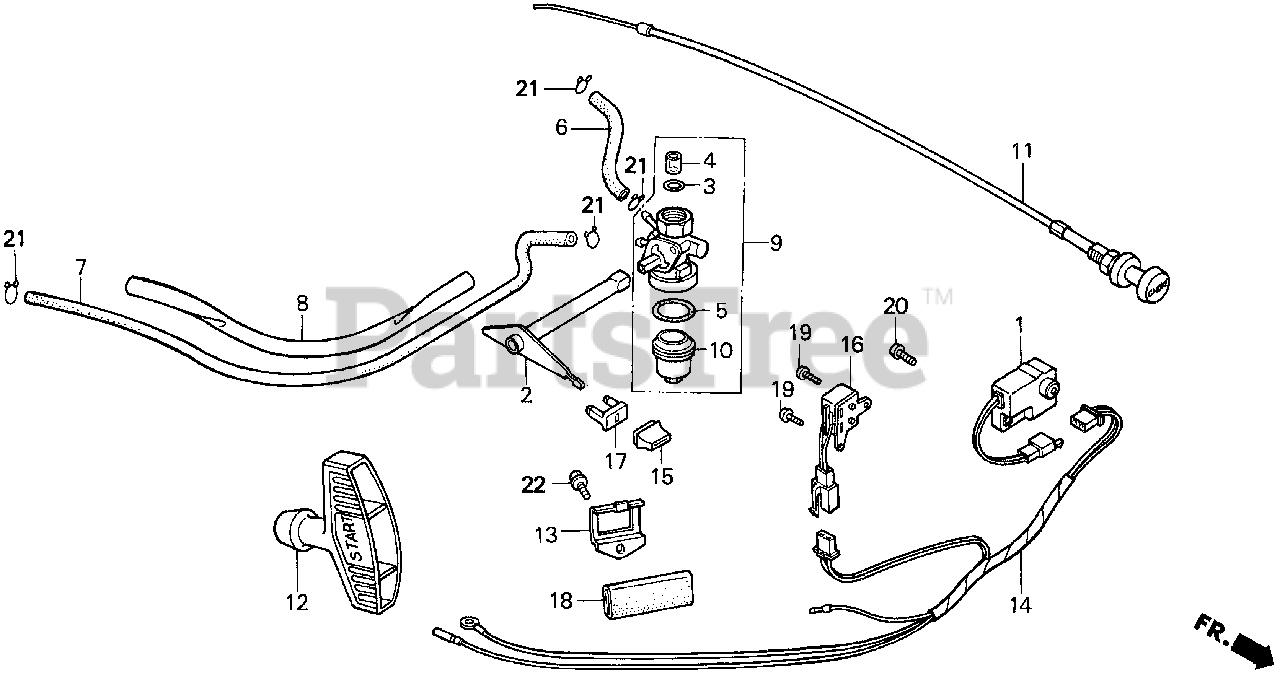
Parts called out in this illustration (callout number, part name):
1	ALERT UNIT, OIL
2	SHAFT, SWITCH VALVE
3	O-RING (NOT AVAILABLE)
4	COLLAR, VALVE SETTING (NOT AVAILABLE)
5	GASKET, FUEL STRAINER CUP
6	TUBE, STRAINER VALVE
7	TUBE ASSY., VALVE CARBURETOR
8	RUBBER, SUPPORTER
9	PETCOCK ASSY.
9	PETCOCK ASSY., FUEL
10	CUP, FUEL STRAINER
11	CABLE, CHOKE
12	GRIP, STARTER
13	COVER, WIRE CLIP
14	SUB-WIRE HARNESS ASSY.
15	KNOB, VALVE LEVER
16	SWITCH ASSY., STOP
17	BUSH, CONTROL KNOB
18	TUBE, WIRE
19	SCREW, PAN (3X8)
20	SCREW, PAN (4X12)
21	CLIP, TUBE (B8)
22	BOLT, FLANGE (6X10)
